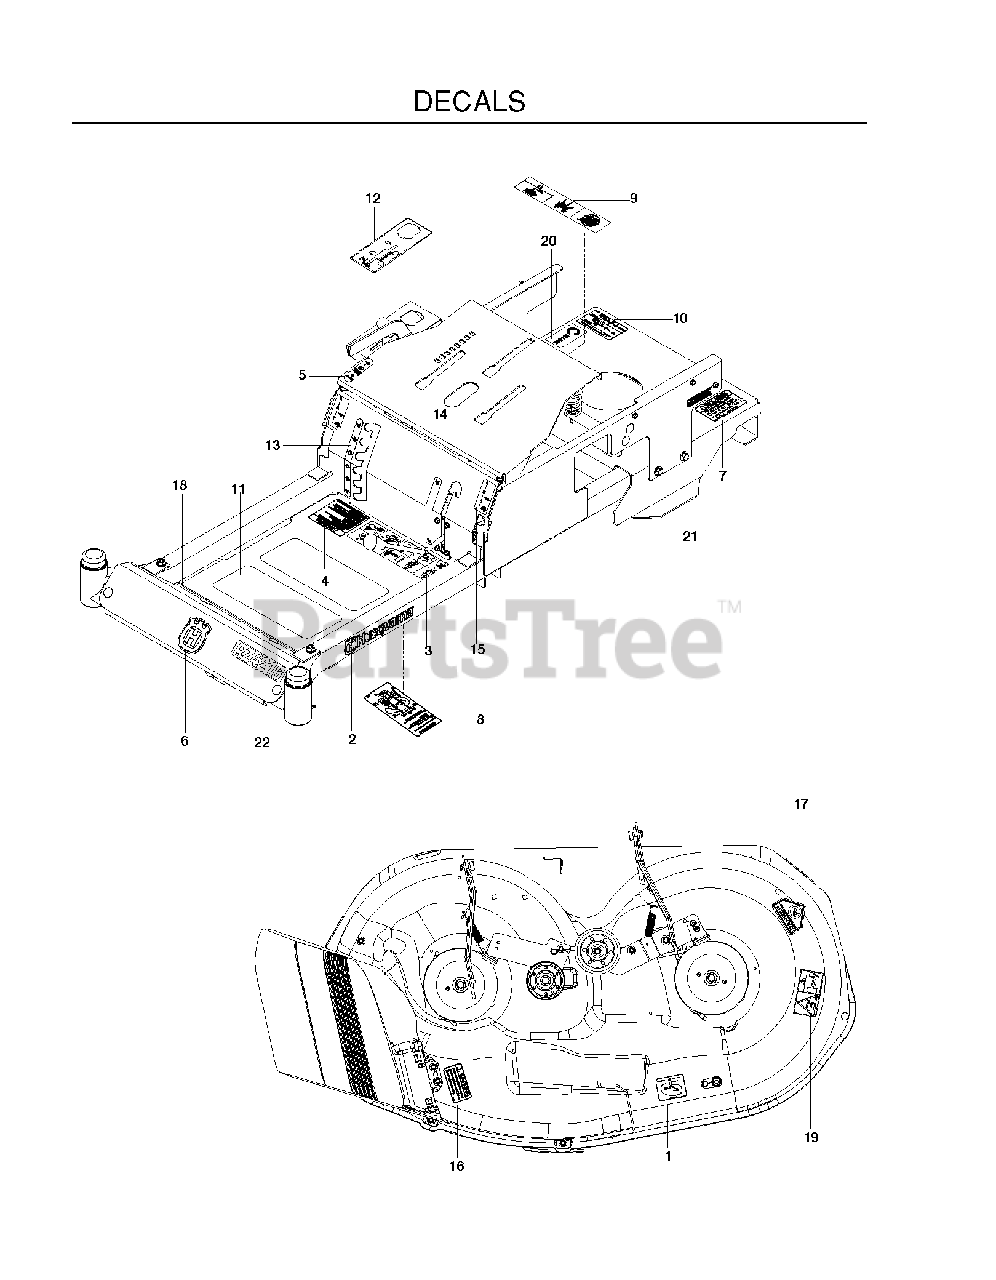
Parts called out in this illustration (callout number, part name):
1	DECAL, BELT ROUTING
2	RP.DECAL.BADGE.170MM.TEXTLOGO
3	DECAL, SAFETY WARNING
4	DECAL, WARNING
5	DECAL, PARK BRAKE
6	DECAL.AUGER.HUSQ.CROWN.SNOW
7	DECAL, PROP. 65
8	DECAL, SERVICE
9	EURO DECAL-BATTERY WARNIN6
10	DECAL, DO NOT TOW
11	ANTI-SKID PAD
12	DECAL, CONTROL PANEL HUS
13	DECAL, DECK HEIGHT
14	DECAL, BLADE ENGAGEMENT
15	DECAL, MOTION CONTROL
16	DECAL, CAUTION
17	DECAL, CPSC
19	DECAL, EURO SEVERING
20	DECAL, ECM, AUSTRALIA
22	DECAL, RZ4216
